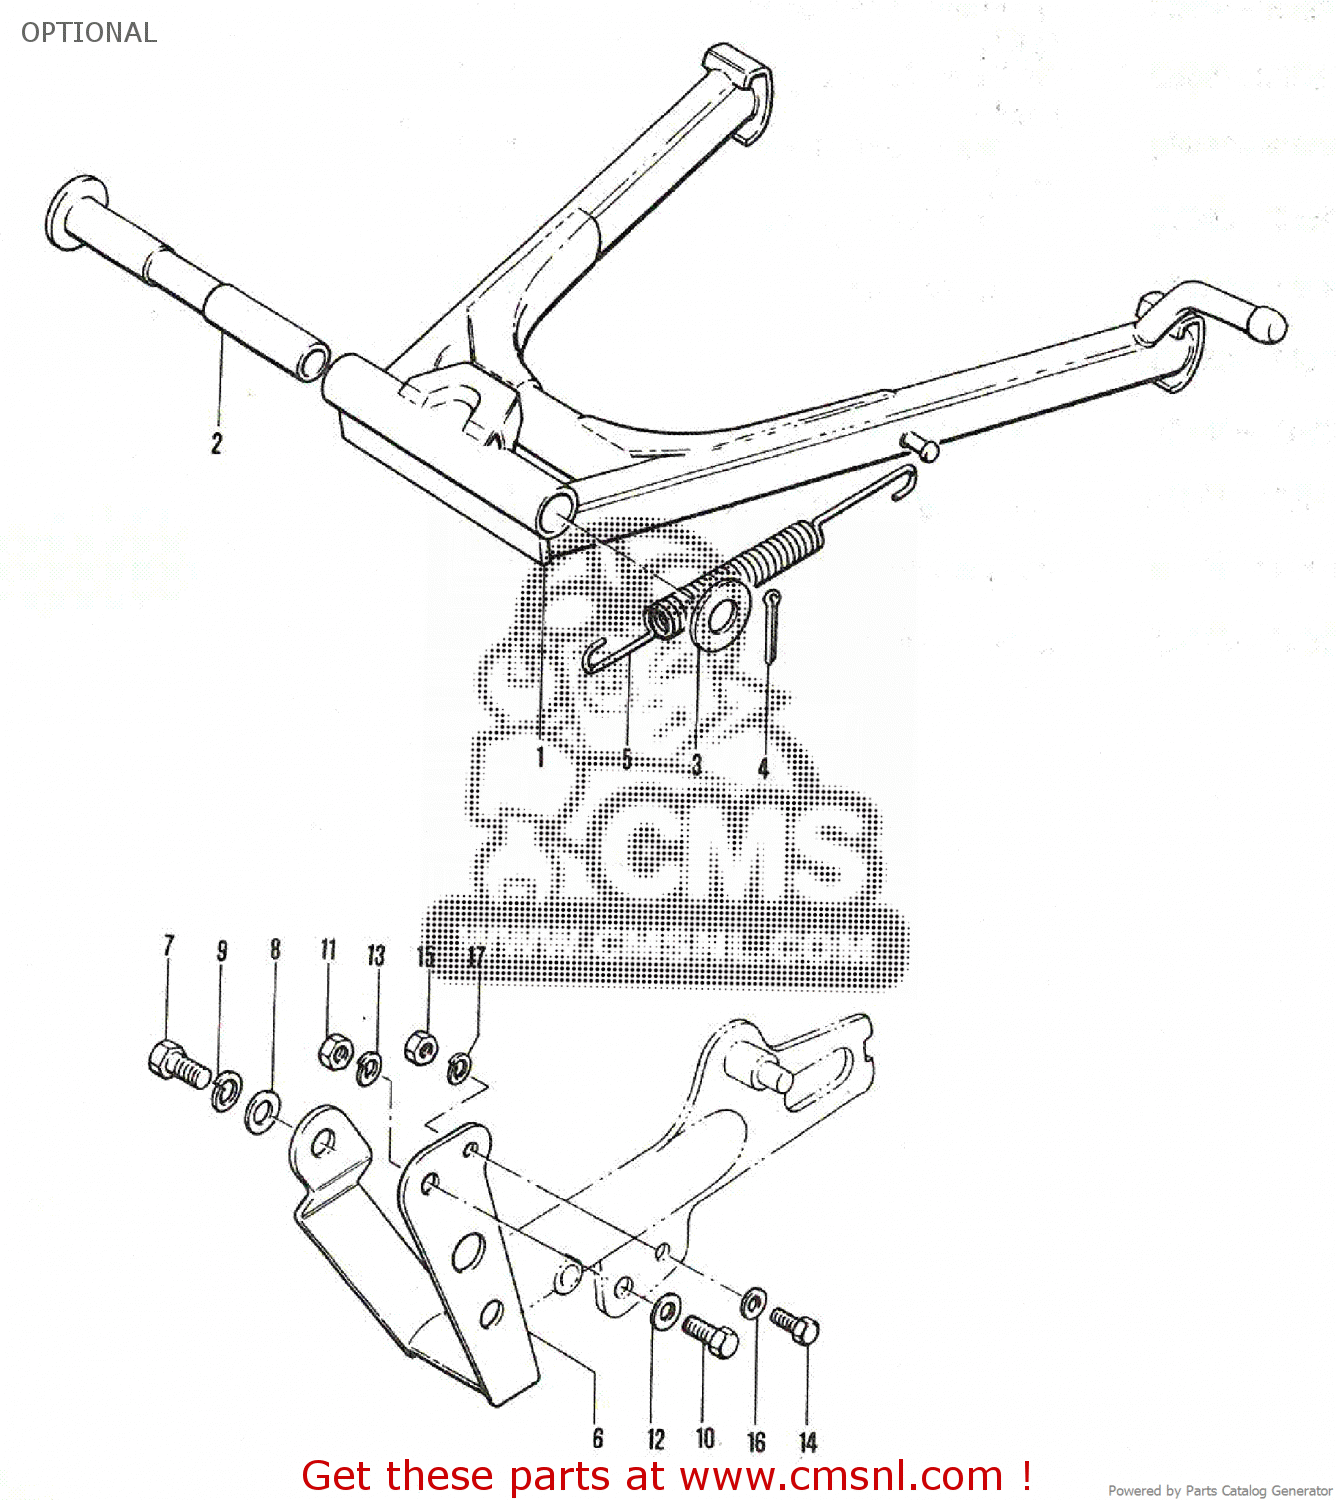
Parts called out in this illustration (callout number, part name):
1	STAND,CENTER
2	CENTER STAND SPACER
3	WASHER(16.5X32X2.3)
4	PIN
5	SPRING
6	CHAIN GUIDE
7	HEXAGON BOLT
8	WASHER
9	LOCK WASHER
10	BOLT
11	NUT
12	WASHER
13	LOCK WASHER
14	BOLT
15	NUT
16	WASHER
17	LOCK WASHER
